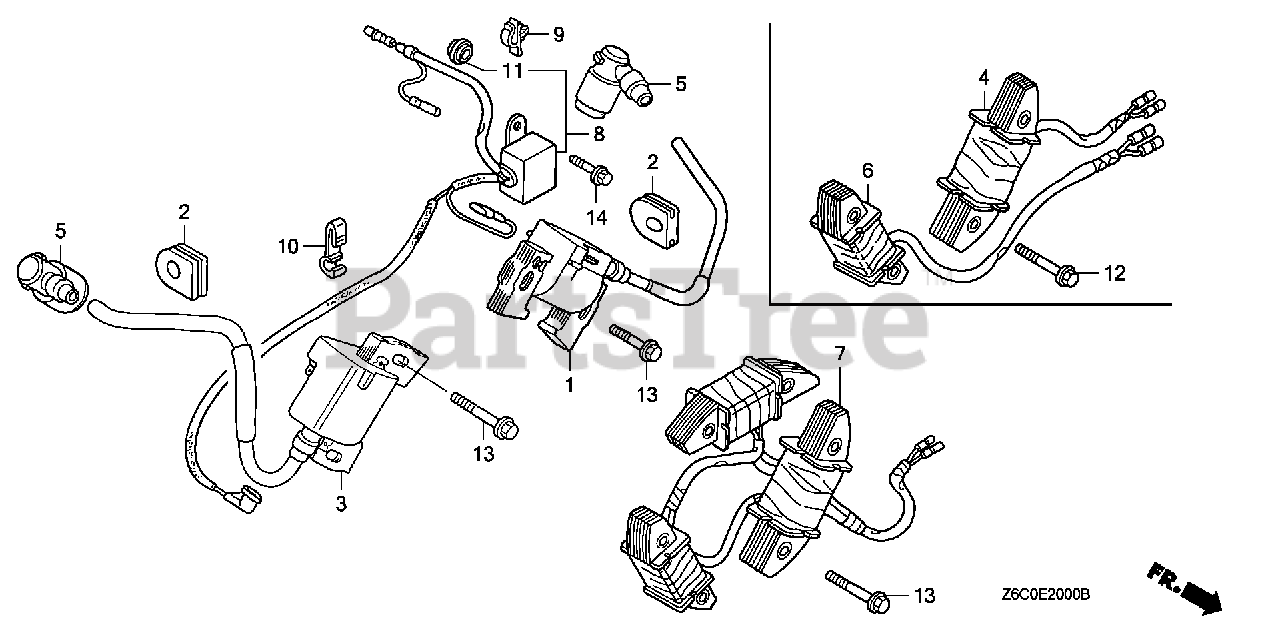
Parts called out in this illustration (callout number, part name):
1	COIL ASSY., IGNITION (200MM) (BLACK)
2	GROMMET, IGNITION WIRE
3	COIL ASSY., IGNITION (215MM) (GRAY)
4	COIL ASSY., CHARGE (12V/3A)
5	CAP ASSY., NOISE SUPPRESSOR
8	DIODE ASSY., ENGINE STOP
9	CLIP, WIRE HARNESS
10	CLAMP, WIRE
11	GROMMET, TOOL
12	BOLT, FLANGE (6X35) (CT200)
13	BOLT, FLANGE (6X32) (CT200)
14	BOLT, FLANGE (6X8)
